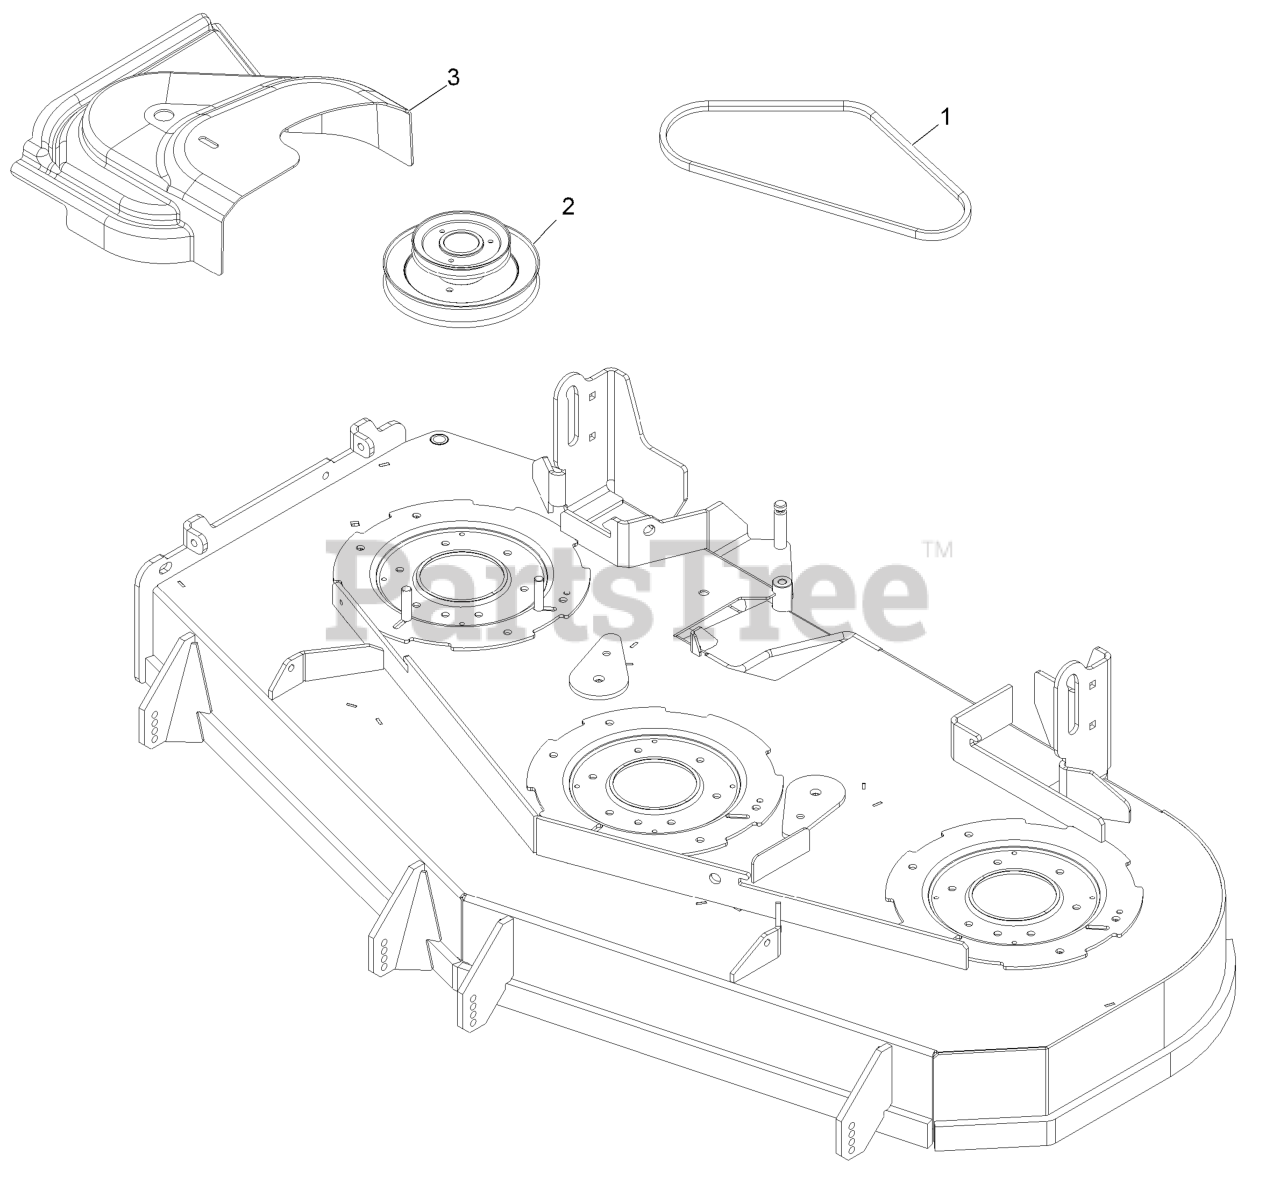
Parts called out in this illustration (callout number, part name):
1	BELT, BLOWER DRIVE 60
2	JACKSHAFT,UV DRIVE 604 SPLINED
3	COVER,BELT UV 60
